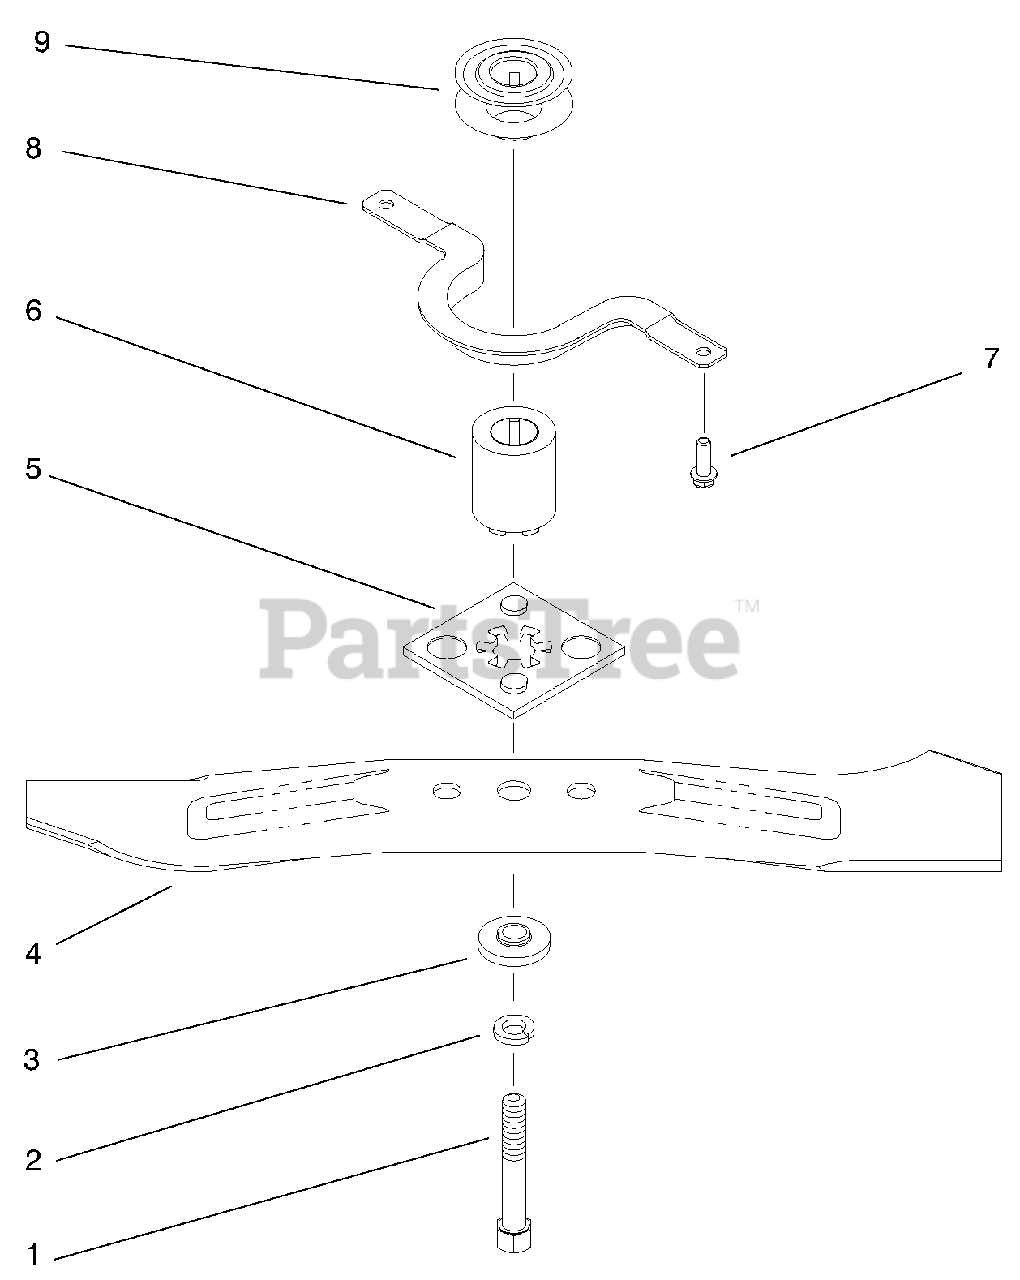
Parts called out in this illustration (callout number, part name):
1	Bolt-Blade
2	Washer-Lock
3	Spacer-Blade
4	Blade 19"
5	Plate-Blade Driver
6	Hub-Blade Driver
7	Screw-HH Tap
8	Guide-Belt Engine
9	Pulley-Driver
